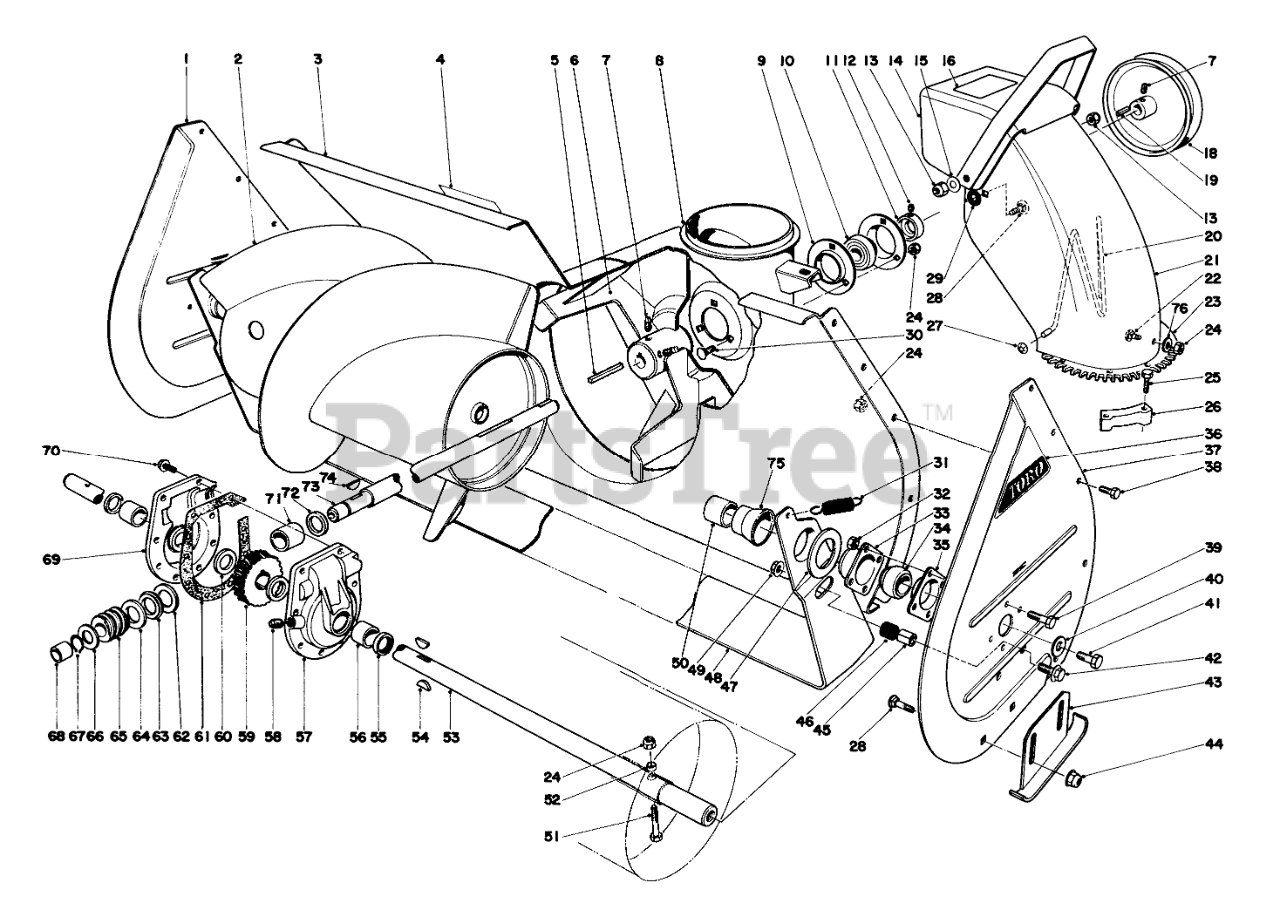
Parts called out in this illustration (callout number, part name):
1	Side Plate
2	Auger R.H.
3	AUGER HSG WA 32" R
4	Decal
6	IMPELLER ASM
7	SCREW-SET, SQH
8	CHUTE RING
9	BRG FLANGE
10	BALL BRG W/COLLAR
11	EXT LOCKING COLLAR
12	SCREW-HSH
13	NUT-LOCK, CONE
14	Deflector (Incl. Ref. #16)
15	WASHER-BELLEVILLE
16	CHUTE WARNING DECAL
18	1/2 X 9.5 DIA PULLEY
19	SQUARE KEY
20	WIRE-CHUTE
21	Upper Chute
22	SCREW-CARR
23	Screw
24	NUT-LOCK, CONE
25	SCREW-TAP
26	RETAINER-CHUTE
27	NUT-PUSH
28	SCREW-CARR
29	WASHER-RUBBER
30	BOLT-CARR
31	SPRING-TENSION
33	BEARING-FLANGE, FRONT
34	BEARING
35	BEARING-FLANGE, REAR
36	AUGER SIDE PLT DECAL
37	Side Plate L. H.
38	SCREW-HH
39	SCREW-HH
40	Flat Washer
41	SCREW-HH
42	SCREW-HHF
43	Skid
44	NUT-HHF, WHIZ
45	SCRAPER STOP SPACER
46	SCRAPER STOP CUSHION
47	SCRAPER BLADE SPACER
48	SCRAPER BLADE 32" R
49	NUT-HF
50	SPACER
51	Auger Bolt
52	SPACER-HUB, AUGER
53	32 AUGER SHAFT
54	KEY-WOODRUFF
55	SEAL-OIL
56	BUSHING
57	Gear Case L.H. (Incl. Ref. #55-56)
58	PLUG-PIPE, SQH
59	GEAR-WORM, 27T
60	WASHER-THRUST
61	Gasket
62	WASHER-THRUST
63	BEARING-THRUST
64	THRUST-WASHER
66	WASHER-THRUST
67	Ring-Snap
68	BUSHING
69	Gear Case R.H. (Incl. Ref. #55-56)
70	SCREW-HWHTF
71	BUSHING-SPECIAL
72	RING-QUAD
73	SHAFT-IMPELLER
74	KEY-WOODRUFF
75	Positioner-Scraper Blade
76	WASHER-PLAIN
